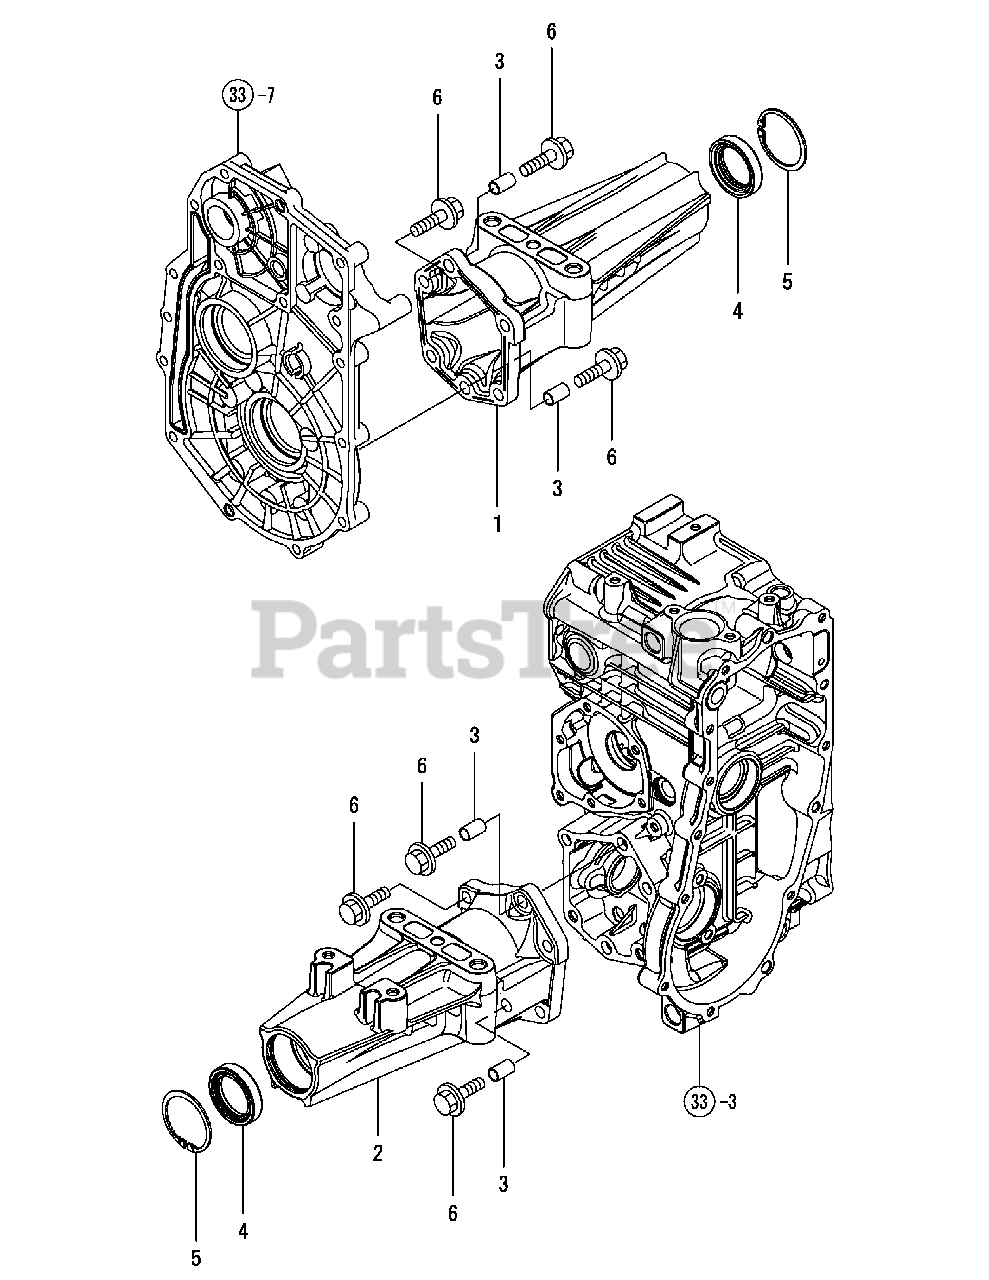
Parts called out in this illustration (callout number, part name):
1	HOUSING, REAR AXLE R
2	HOUSING, REAR AXLE
3	COLLAR, 10X12X20
4	SEAL, TC395511
6	BOLT M10X 35 PLATED
